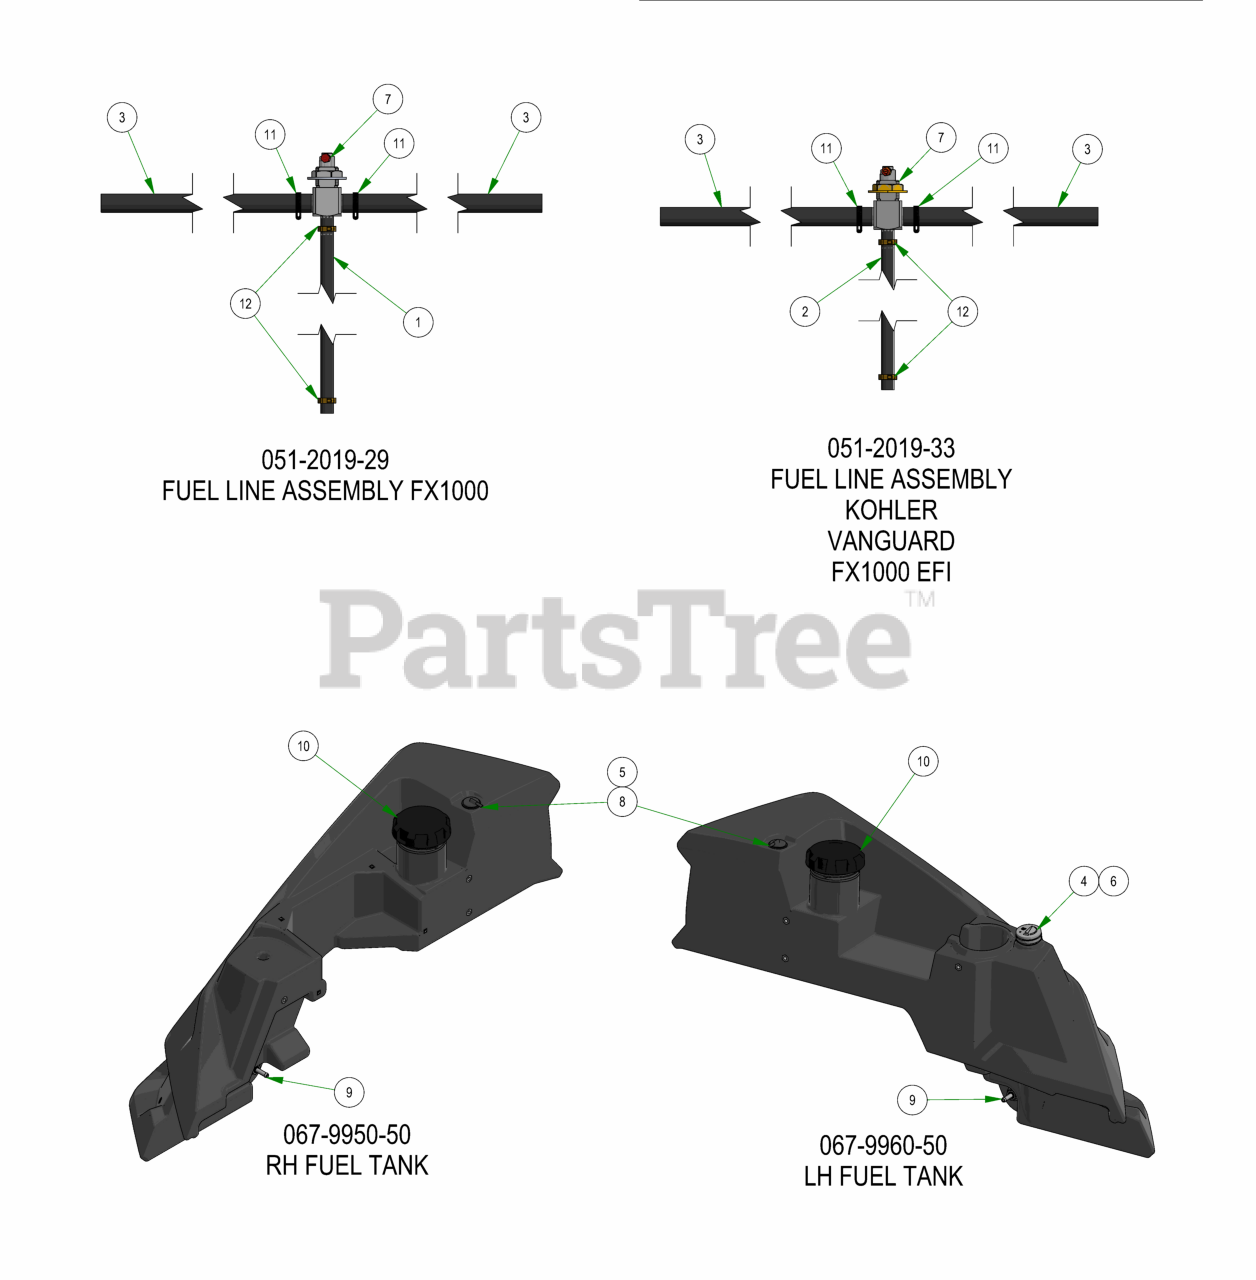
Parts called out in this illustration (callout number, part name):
1	1/4" Fuel Line Hose
2	1/4" Fuel Line Hose
3	5/16" fuel line hose
4	Fuel Gauge with Grommet
5	Roll Over Valve Grommet
6	Fuel Gauge Grommet
7	3 Way Fuel Shut-Off Valve 5/16 x 5/16 x 1/4
8	Rollover Valve
9	Fuel Pick-up
11	5/16 Fuel Line Clamp
12	1/4 Fuel Hose Clamp
